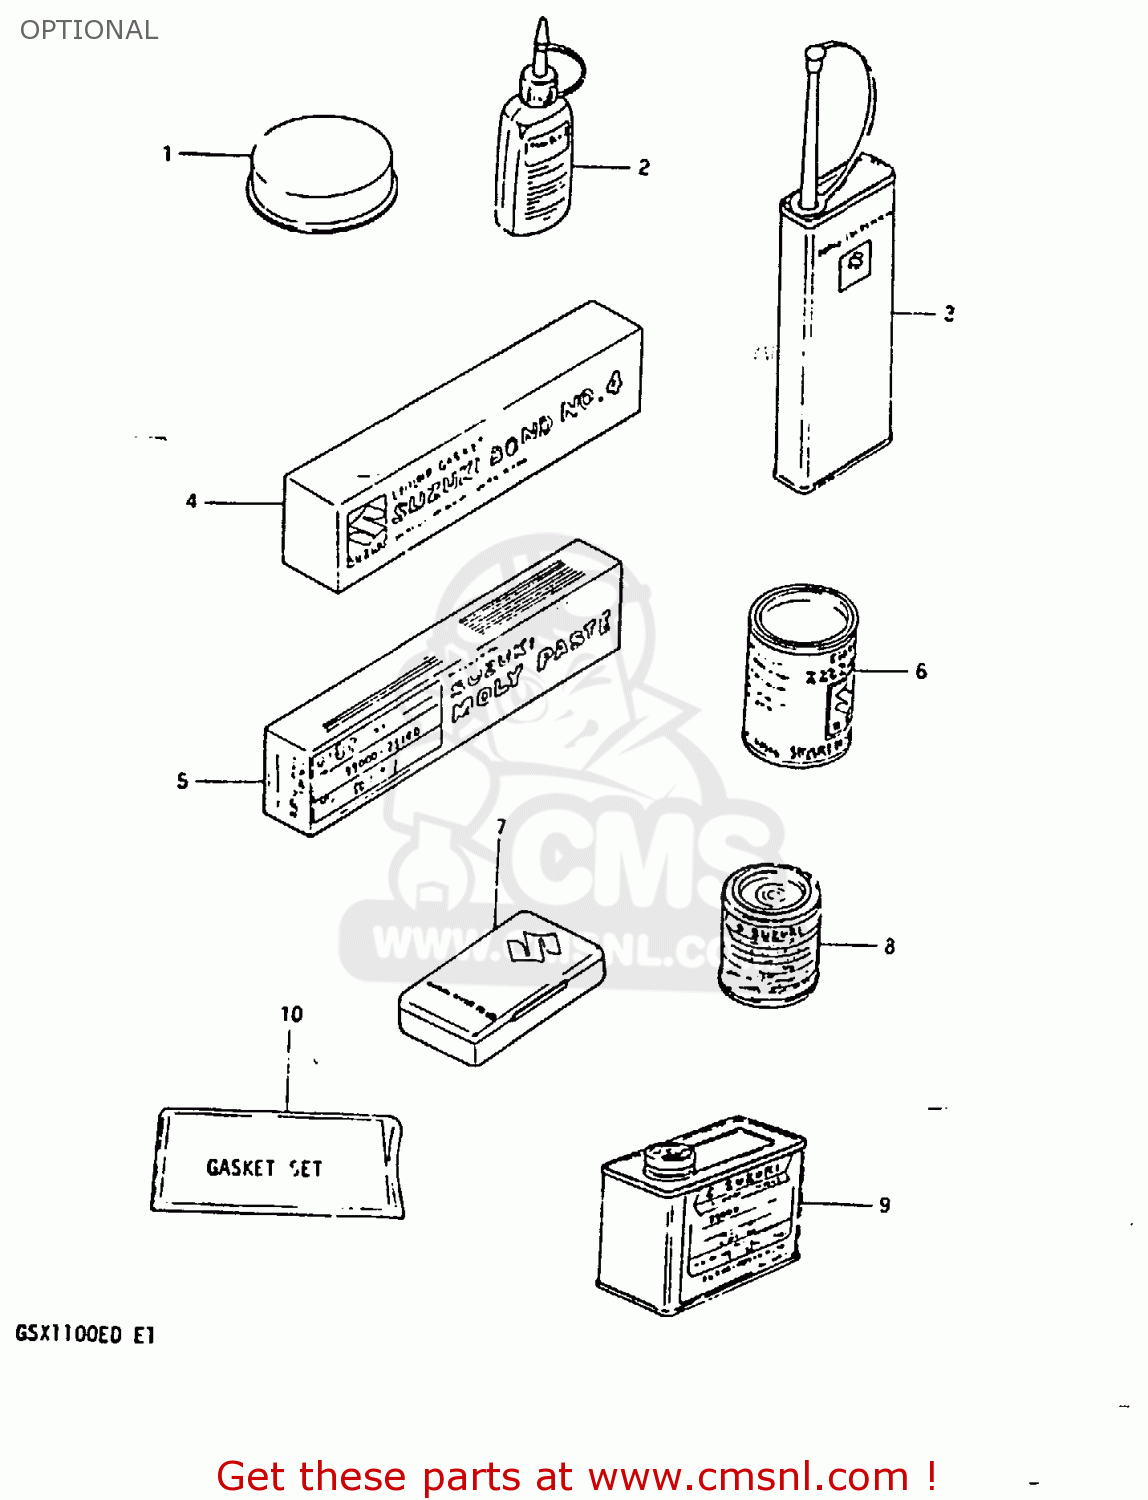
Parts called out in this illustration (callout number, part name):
1	GREASE,PBC FOR BRK PAD 20G
2	THREAD LOCK NO.1342
3	THREAD LOCK NO.1401 CLEAR 200G
4	BOND 1104
5	SUZUKI MOLY PASTE
6	GREASE(C)EP2 LITHIUM 150G
7	TUBE REPARING TOOL
8	PAINT,BLACK
9	PAINT (BLACK SEMI-GLOSS NO.2)
10	GASKET SET
